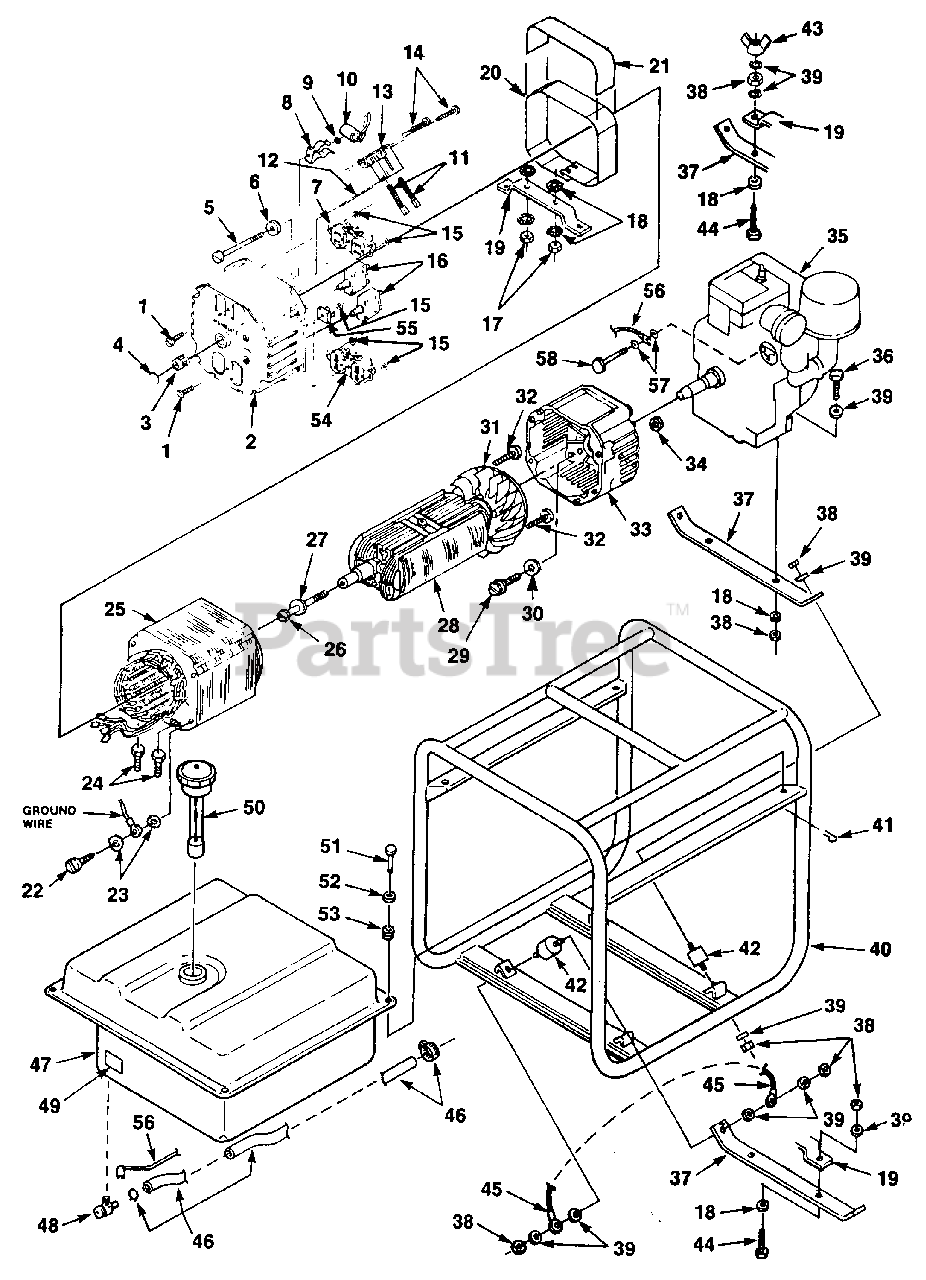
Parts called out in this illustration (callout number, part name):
1	SCREW- Mach. Pan Hd.
2	BRUSH HEAD
3	BEARING- Needle
4	PLUG- Expansion
5	BOLT- Stator
6	WASHER- Flat
7	RECEPTACLE- Duplex (Nema 5-15R)
8	CLIP- Spring
9	WASHER- Shaft retention
10	CAPACITOR w/Lead
11	BRUSH
12	PIN- Retainer
13	HOLDER- Brush
15	WASHER- Shaft retention
16	BREAKER- Circuit (15 amp.)
17	NUT- Hex (5/16-18)
18	WASHER- Lock (Int./Ext.)
19	BRACKET- Gen Mtg
20	WRAPPER- Stator
21	DECAL- Warning
23	WASHER- Lock (Int / Ext )
24	SCREW (5/16 x 3/4")
25	STATOR & CORE
26	BOLT- Rotor
27	WASHER- Lock (5/16")
29	SCREW- Cap hex hd
30	WASHER- Lock (Int./Ext.)
31	FAN ASSEMBLY
32	SCREW- Pan hd
33	END BELL
34	NUT- Hex
35	ENGINE
36	SCREW- Cap hex ho
37	SUPPORT- Engine
38	NUT- Hex
39	WASHER- Lock (Int.)
40	ROLL CAGE
41	PIN- Cotter
42	ISOLATOR- Vibration
43	NUT- Wing
44	SCREW- Mach. hex hd
45	GROUND STRAP
46	FUEL LINE ASSEMBLY
47	FUEL TANK
48	VALVE- Fuel
49	DECAL- Fuel valve
50	CAP- Fuel
51	PIN- Clevis
52	WASHER- Flat
53	GROMMET- Isolator
54	RECEPTACLE- 240 V (Nema 5-15R)
55	RECTIFIER
56	GROUND STRAP
57	WASHER- Lock
